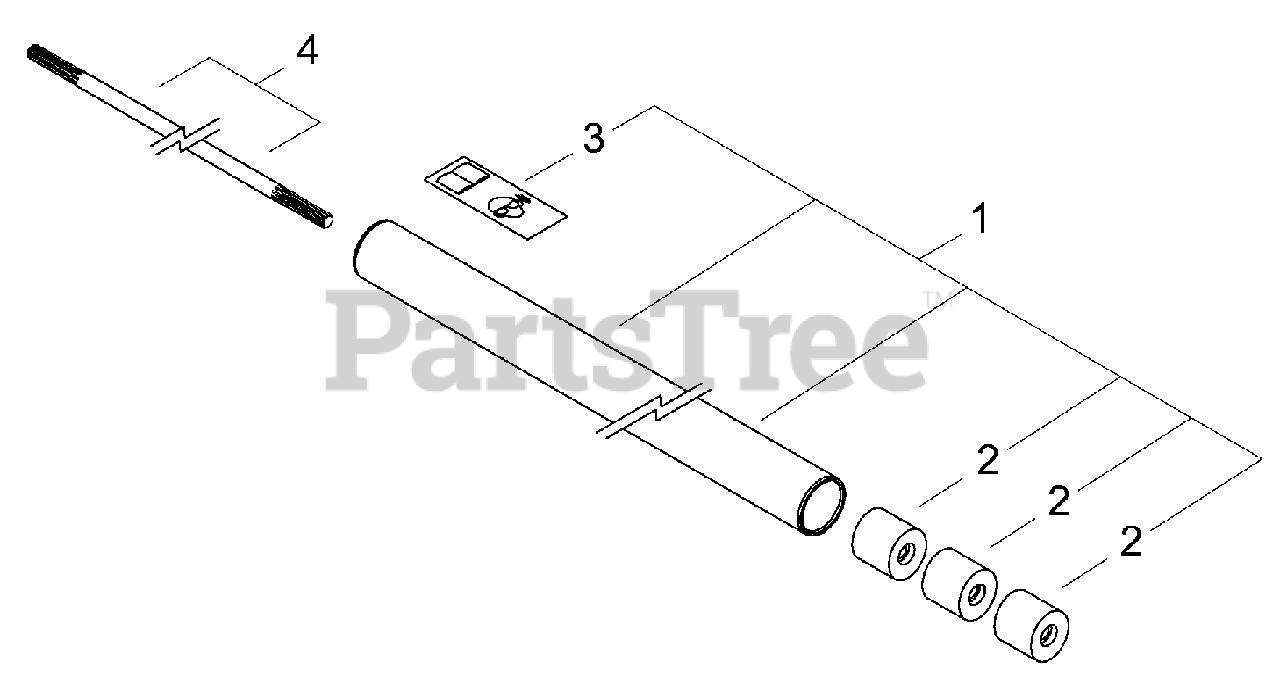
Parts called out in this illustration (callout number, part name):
1	OUTER TUBE ASSY
2	BUSHING
3	LABEL - CAUTION
4	PIPE, MAIN
